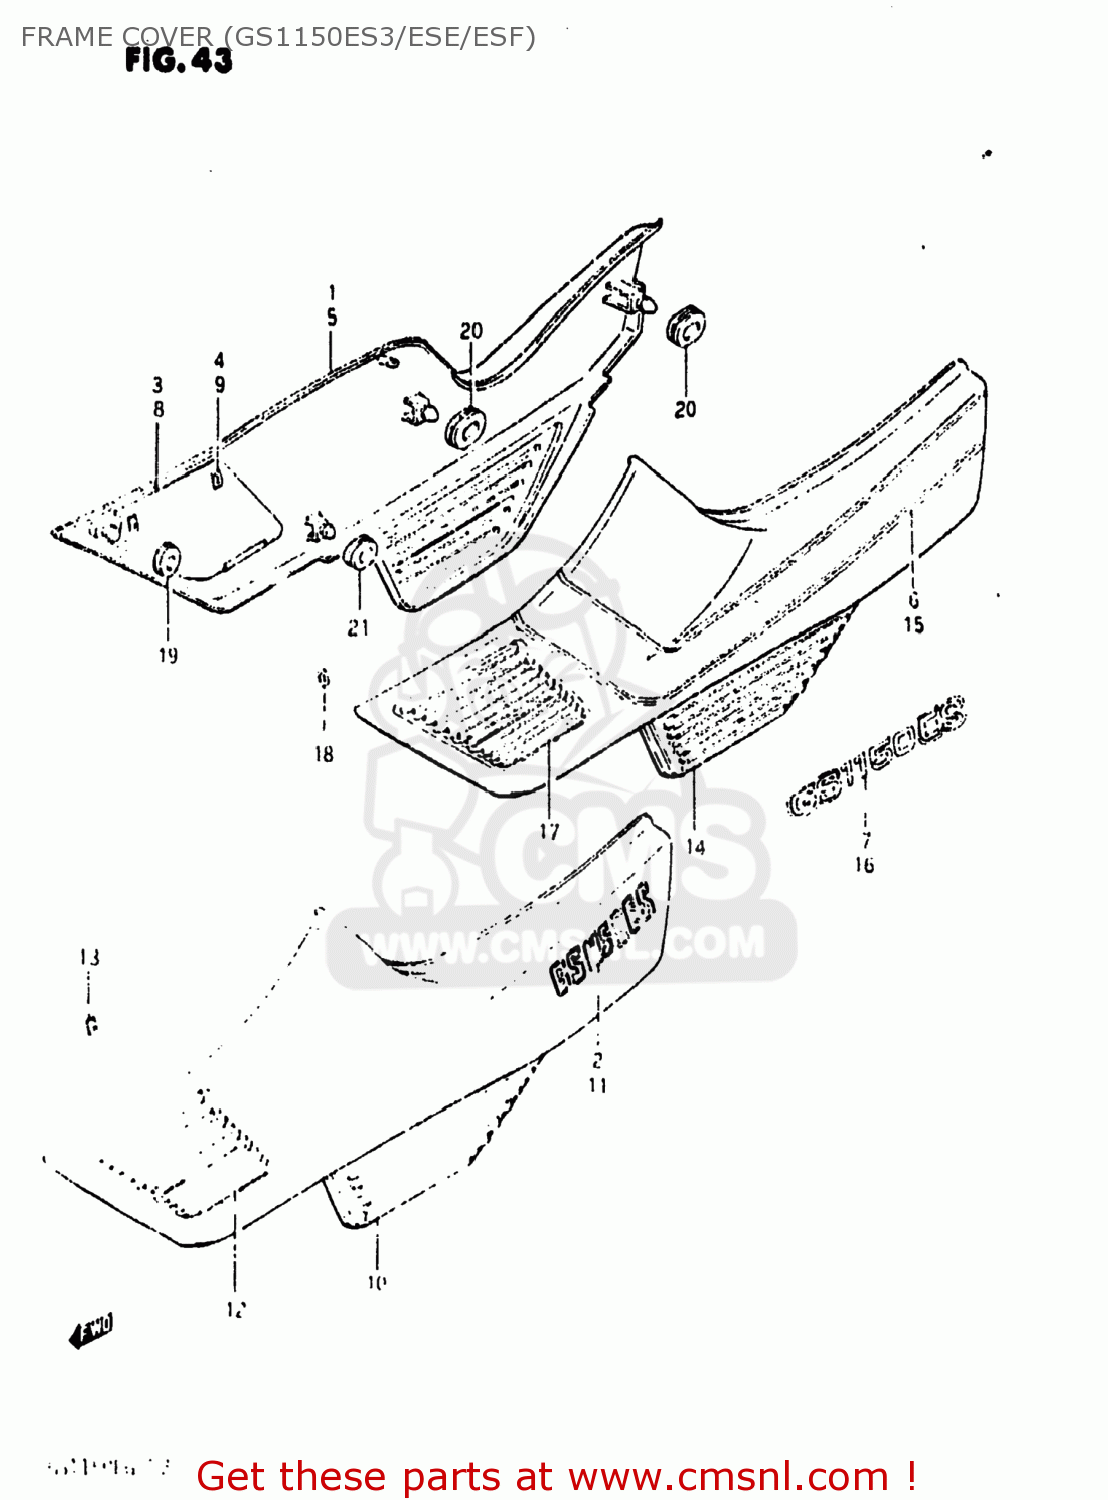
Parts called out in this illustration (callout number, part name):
1	COVER,FRAME,RIGHT
2	EMBLEM
3	COVER,FRAME,RIGHT
4	NUT
5	COVER ASSEMBLY,FRAME BODY
6	TAPE SET,FRAME COVER
7	EMBLEM
8	COVER,FRAME,RIGHT
9	NUT
10	COVER ASSEMBLY,FRAME,LEFT
11	EMBLEM
12	COVER,FRAME,RIGHT NO.1
13	NUT
14	COVER, FRAME LH
15	TAPE,FRAME COVER
16	EMBLEM
17	COVER,FRAME,RIGHT NO.1
18	NUT
19	CUSHION
20	CUSHION
21	CUSHION
